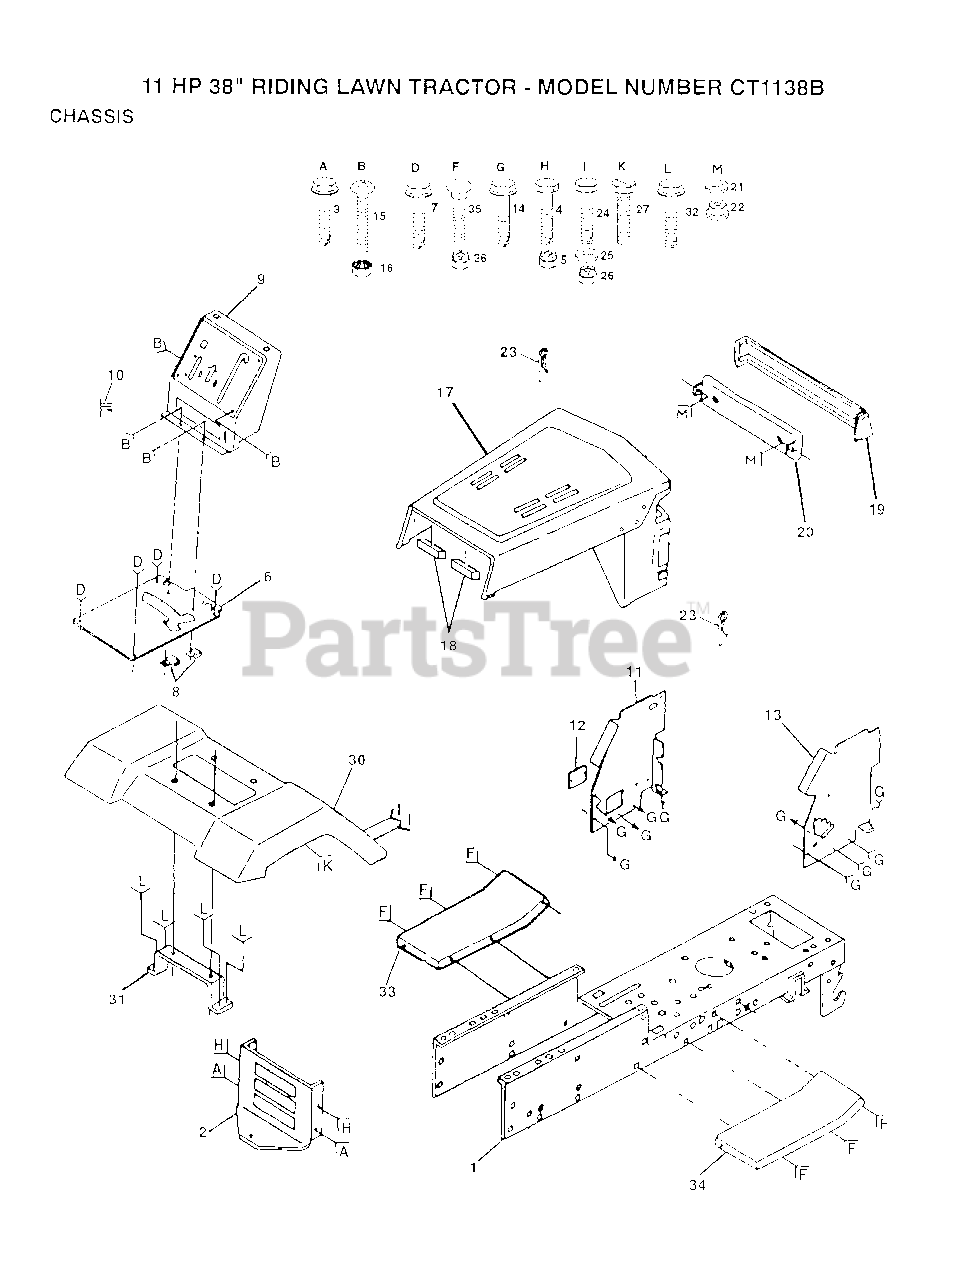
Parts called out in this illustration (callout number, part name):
1	CHASSIS WELDMENT
2	DRAWBAR LT/YT
3	SCREW
7	SCREW LT
8	CLIP T
10	PLUG BUTTON T
11	PANEL DASH LH
12	COVER ACCESS
14	SCREW LT
15	SCREW
17	HOOD/GRILL ASM
19	LENS SERVICE KIT
21	WASHER PM
22	PAL NUT LT
23	SPRING.RETAINER
25	WASHER
27	SCREW LT
30	FENDER
32	SCREW
33	FOOTREST LH
34	FOOTREST RH
35	BOLT
